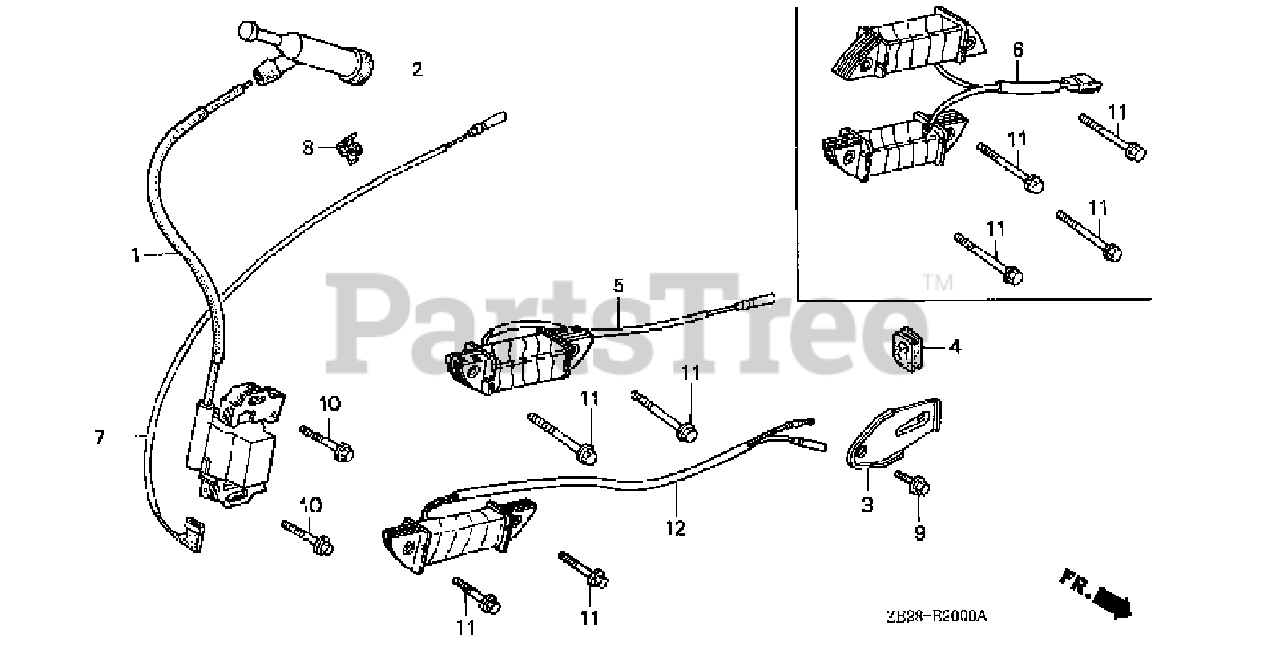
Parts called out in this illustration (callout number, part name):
1	COIL ASSY., IGNITION
2	CAP ASSY., NOISE SUPPRESSOR
4	GROMMET, WIRE
7	WIRE, STOP SWITCH (370MM)
10	BOLT, FLANGE (6X28)
